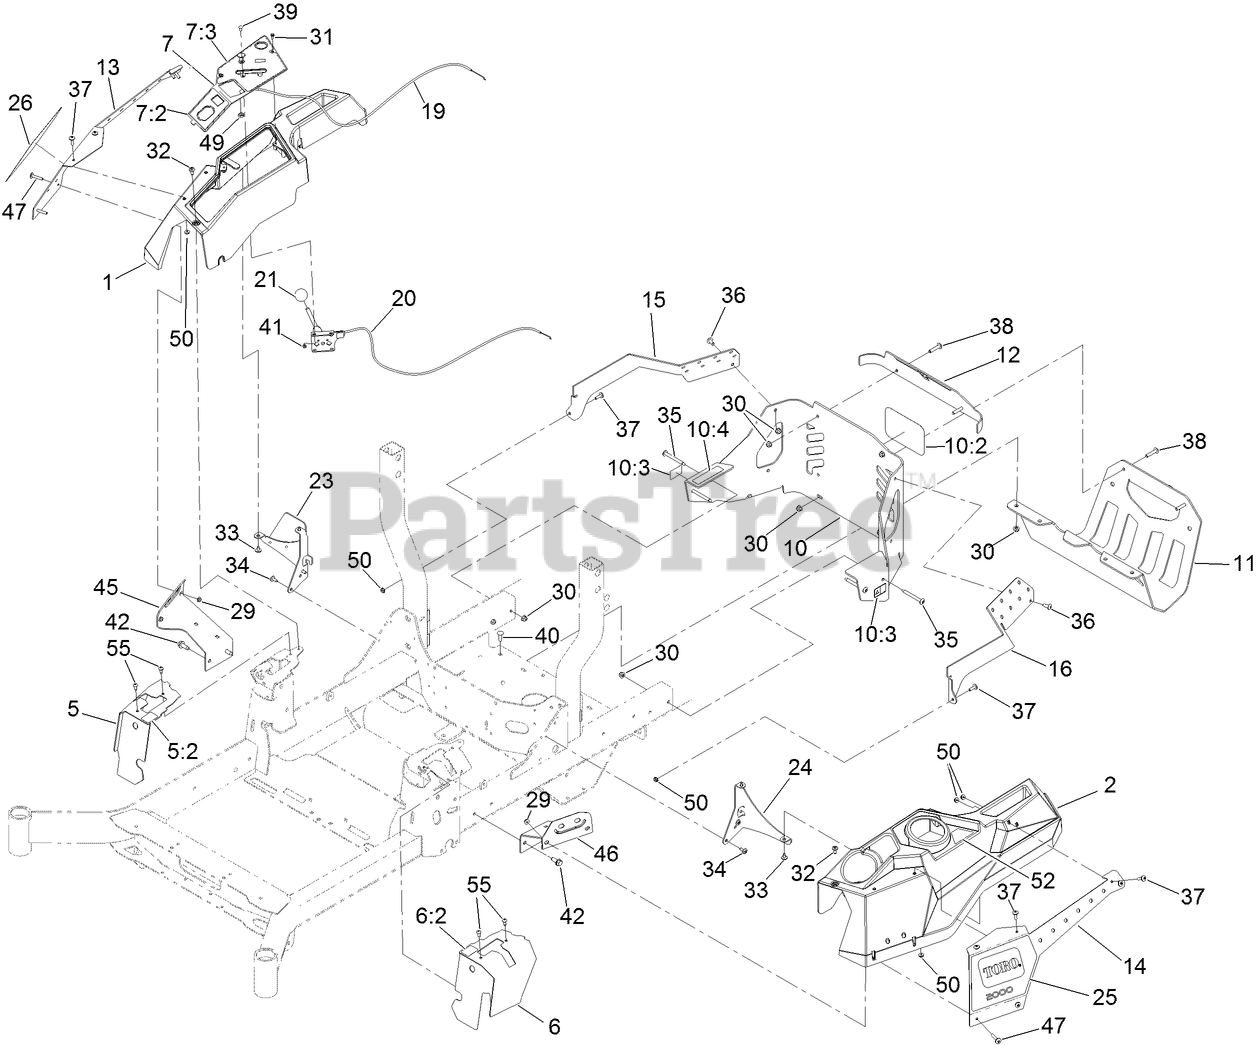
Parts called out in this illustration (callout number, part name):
1	CONSOLE-RH
2	CONSOLE-LH
5	COVER - CONTROL, MOTION
5:2	DECAL-MOTION CONTROL
6	COVER - CONTROL, MOTION
6:2	DECAL-MOTION CONTROL
7	CTRL PANEL ASM
7:2	DECAL-PANEL, CONTROL
7:3	DECAL-PANEL CTRL
10	REAR GUARD ASM
10:2	DECAL
10:3	DECAL-WARNING
10:4	DECAL-ARRESTOR, SPARK
11	GUARD-MUFFLER [BLACK]
12	TRIM-UPPER REAR
13	COVER,POD RH
14	COVER [BLACK]
15	BRACKET-GUARD, RH
16	BRACKET-GUARD, LH
19	CABLE-CONTROL, CHOKE
20	CABLE-CONTROL, THROTTLE
21	KNOB-BALL
23	SUPPORT-CONSOLE, RH
24	BRACKET-CONSOLE, LH
25	DECAL-2000, LH
26	DECAL-2000, RH
29	NUT-HF
30	NUT-HF, NI
31	SCREW-HWH
32	SCREW-SHOULDER
33	SCREW-TORX
34	SCREW-TORX
35	SCREW-TORX
36	SCREW-TORX
37	SCREW-TRUSS
38	SCREW-TORX
39	BOLT-CARR
40	SCREW-CARR
41	NUT-LOCK, NI
42	SCREW-FORMING, THREAD
45	BRACKET-SUPPORT, POD (RH)
46	BRACKET-SUPPORT, POD (LH)
47	SCREW-TRUSS
49	NUT-HJ
50	NUT-KEPS
52	DECAL-FILL, FUEL
55	SCREW-TPH THD FORM
